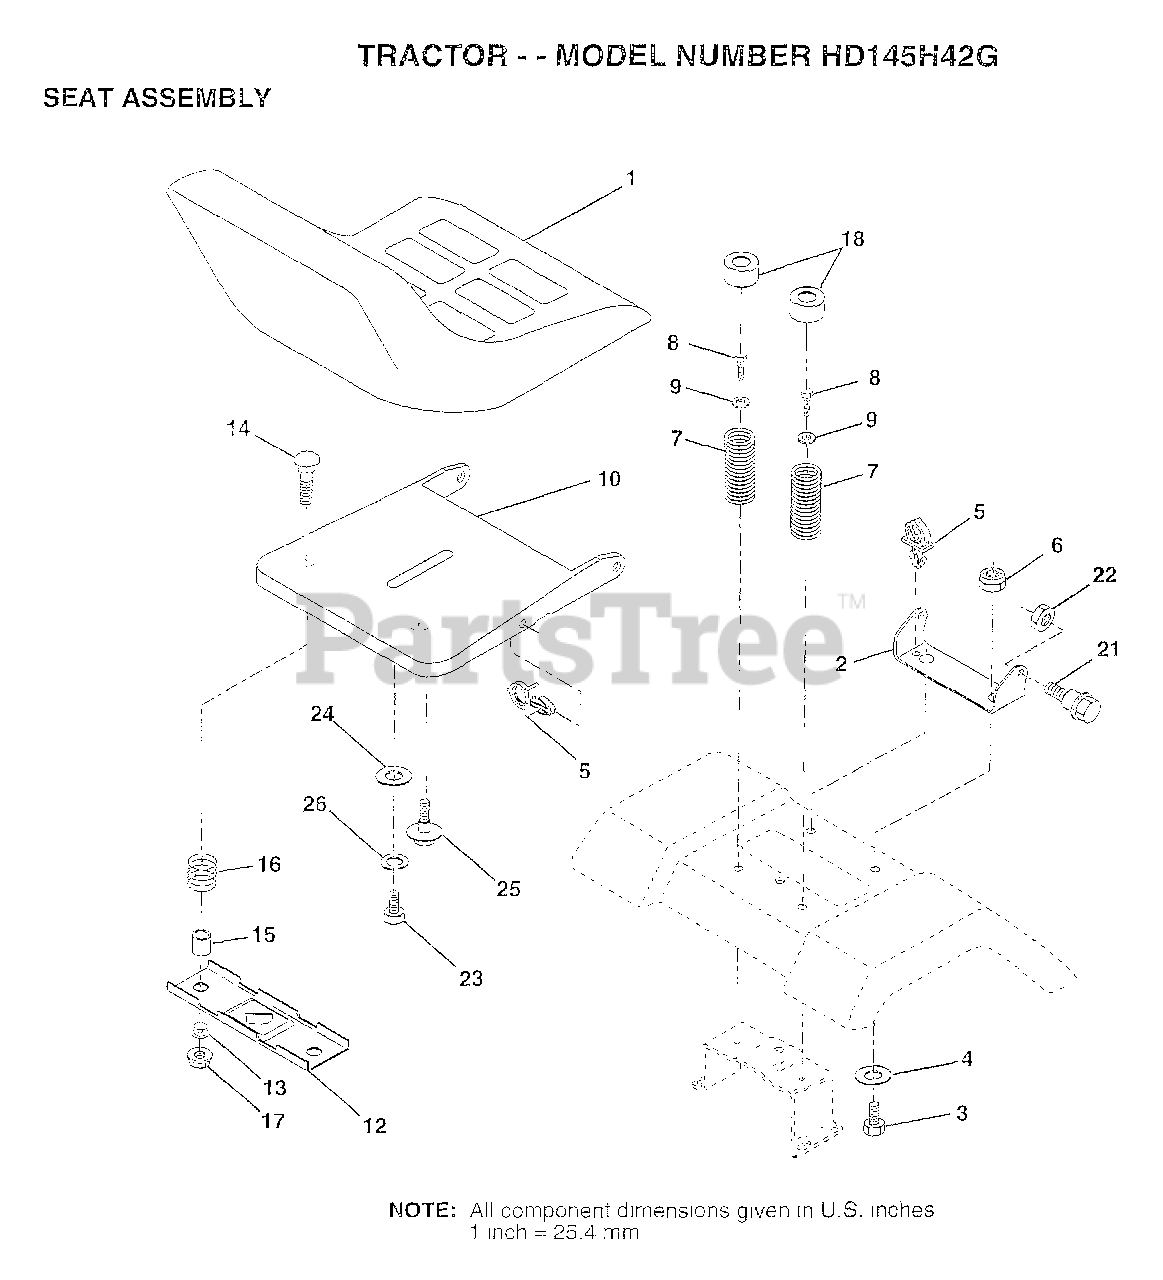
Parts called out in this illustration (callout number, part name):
1	SEAT
2	BRACKET PVT SEAT
3	BOLT
4	WASHER PM
5	CLIP.PUSH-IN.HING
6	NUT
7	SPRING COMPRESSIO
8	SCREW GTV
9	WASHER
10	PAN-SEAT
12	BRKT SWITCH
13	BUSHING
14	BOLT-RD HD SQ NK
15	SPLIT SPACER
16	SPRING
18	CAP SPRING
21	"BOLT,SHOULDER"
23	BOLT
24	WASHER
25	"BOLT,SHOULDER"
26	LOCKWASHER
